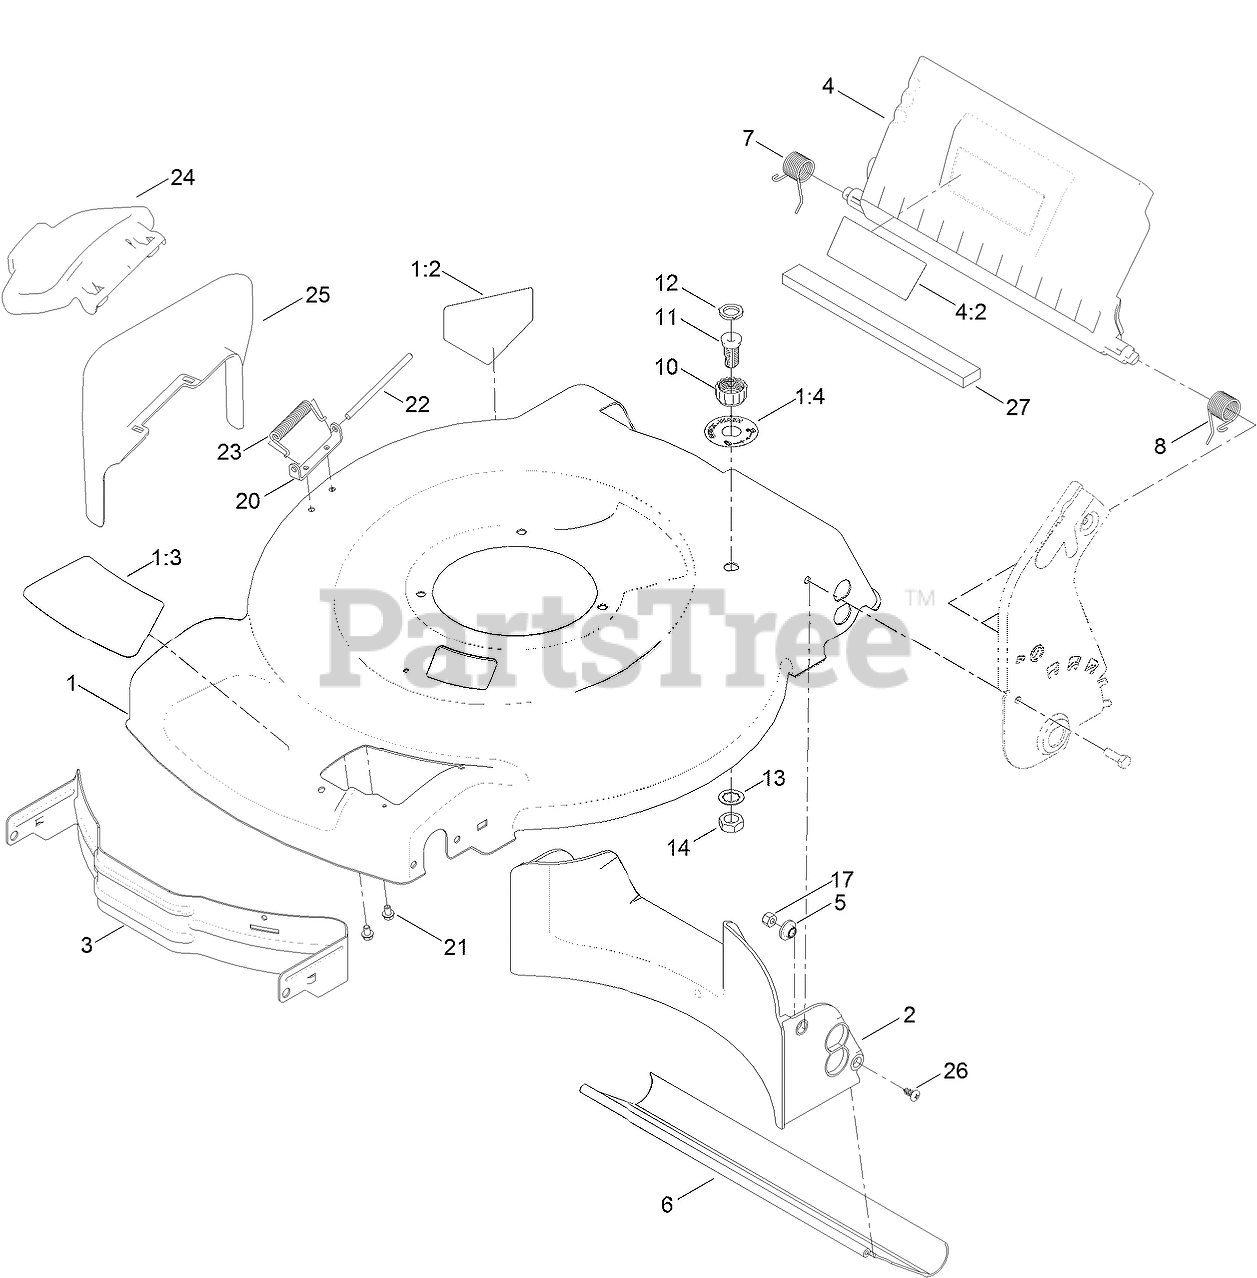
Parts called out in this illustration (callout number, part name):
1	HOUSING ASM
1:2	DECAL-DANGER
1:3	DECAL-DECK, RECYCLER
1:4	DECAL-PORT, WASHOUT
2	BAFFLE-REAR
3	BAFFLE-FRONT
4	REAR DEFLECTOR ASM
4:2	LINKAGE, EQUALIZER
5	WASHER-STEPPED, BAFFLE
6	SHIELD-TRAILING
7	SPRING-TORSION
8	SPRING-TORSION
10	COUPLING-HOSE, WASHOUT PORT
11	PORT-WASHOUT
12	WASHER-SEAL, WASHOUT PORT
13	WASHER-TOOTH, INTERNAL
14	NUT-JAM
17	NUT-LOCK, NI
20	BRACKET-COVER
21	SCREW-HWH
22	ROD-COVER
23	SPRING-TORSION
24	DEFLECTOR-SIDE
25	CHUTE-DISCHARGE, SIDE
26	SCREW-PTH
27	FOAM-SEAL
